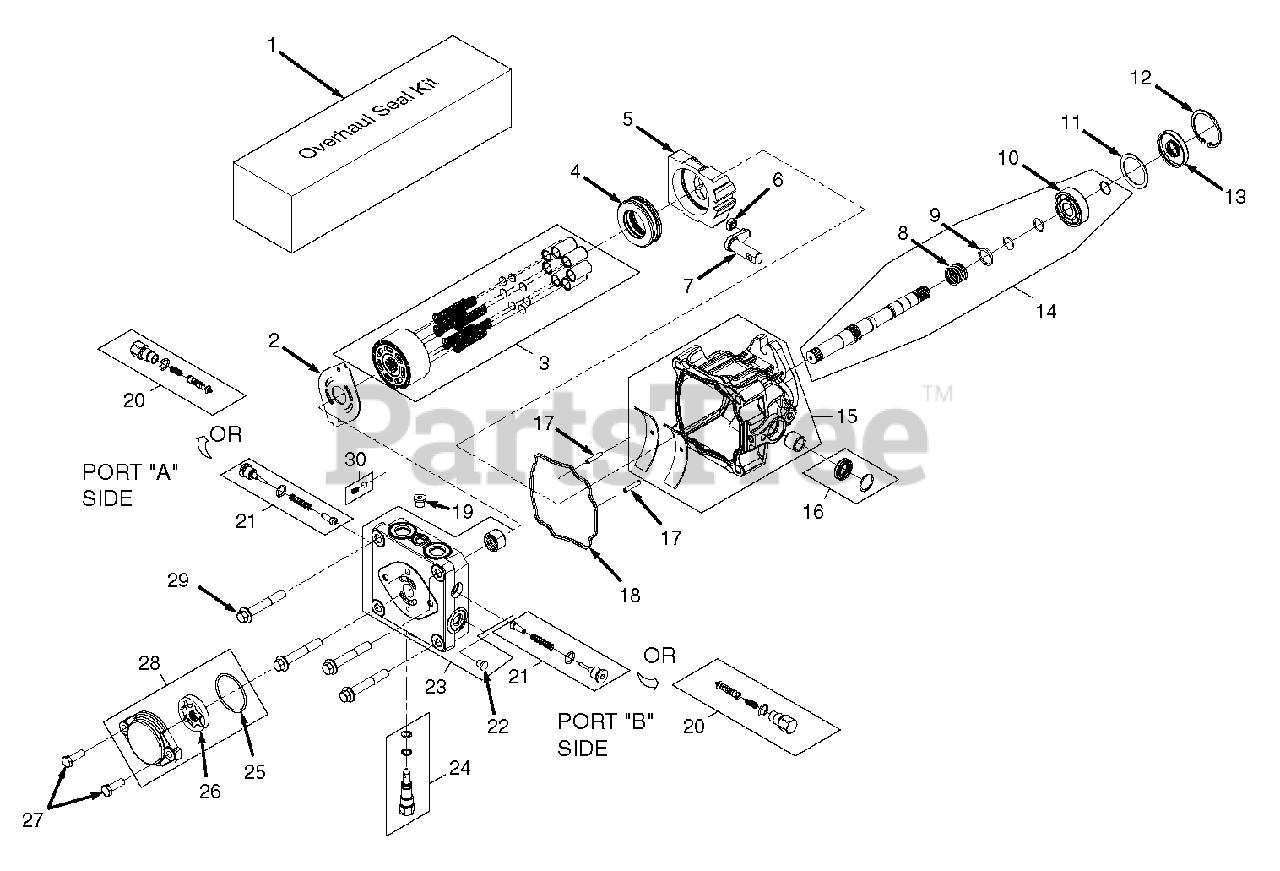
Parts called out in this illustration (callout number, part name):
1	Overhaul Seal Kit
2	Valve Plate
3	Cylinder Block Kit - 16cc
4	Thrust Ball Bearing Assembly
5	Variable Swashplate
6	Slot Guide
7	Trunnion Arm
8	Block Spring
9	Block Thrust Washer
10	Shaft Ball Bearing
12	Retaining Ring
14	Kit, Pump Shaft
15	Housing Kit
16	Trunnion Seal Kit
18	O-Ring
19	Straight Thread Plug
20	Shock Valve Kit (.031 Orifice)
21	Shock Valve Kit (.024 Orifice)
22	Straight Thread Plug
23	End Cap Kit
24	Bypass Valve Kit
26	Gerotor Assembly (.19 cu.in./rev.)
27	Socket Head Cap Screw (M8 x 1.25-25mm)
28	Charge Pump Kit (.19 STD. Splined)
29	Hex Screw, Flanged Head (M10 x 1.50-65mm)
30	Charge Relief Kit
